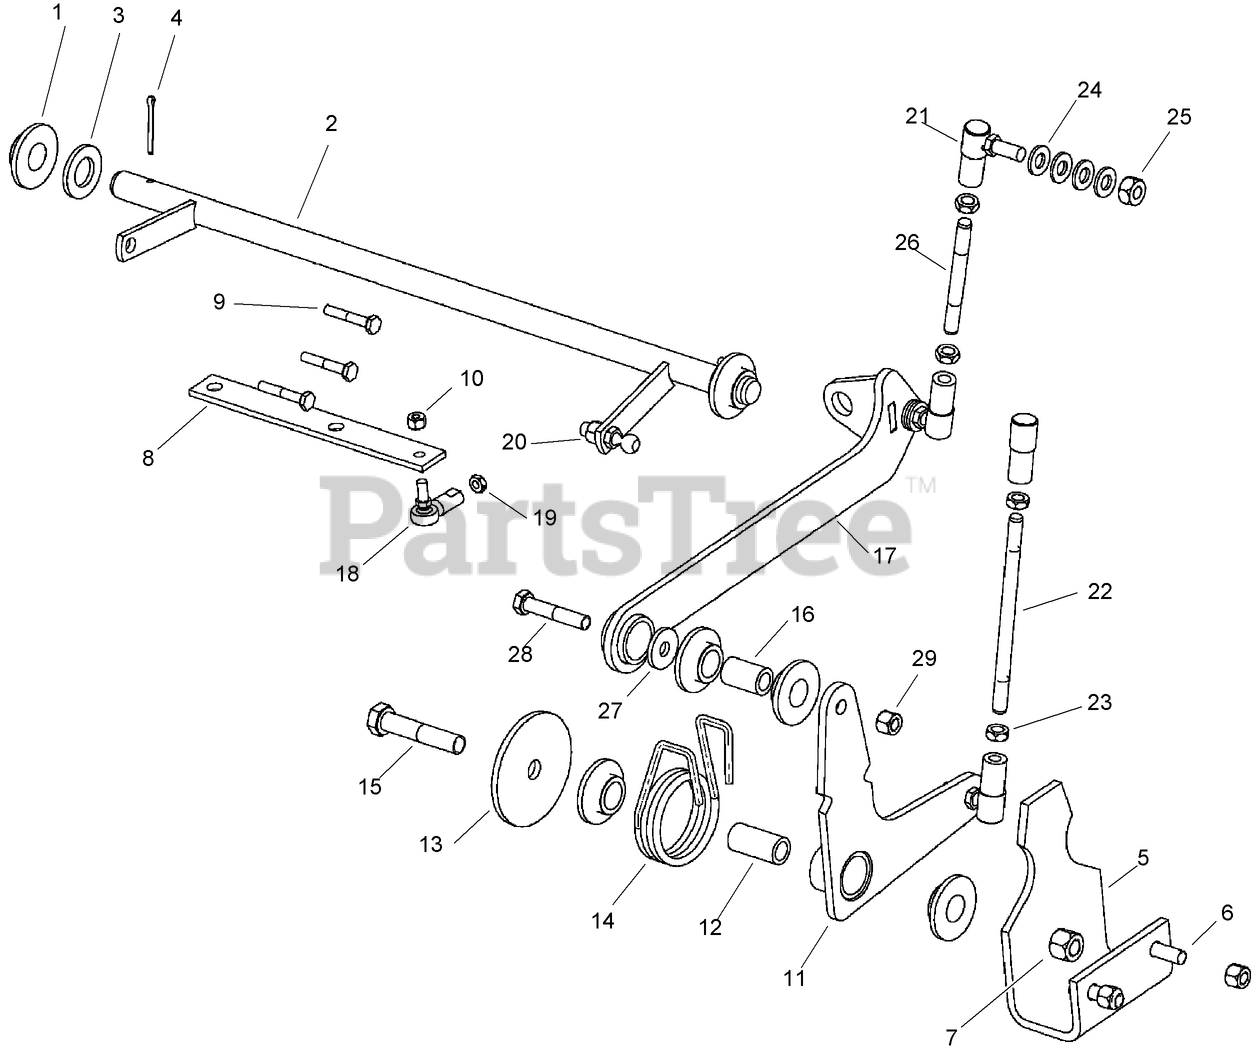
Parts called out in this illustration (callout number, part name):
1	BUSHING-INSERT, PLASTIC
2	WELDMENT-Control Shaft
3	WASHER-FLAT
4	PIN-Cotter, 1/8 x 1-1/4 in ZN
5	CHANNEL-Bellcrank Mounting
6	BOLT
7	NUT-HEX
8	LEVER-Pump Control
9	SCREW-HH
10	NUT-Prev Trq 1/4 GRA CAD DIRECT
11	PIVOT-BELLCRANK
13	WASHER-Special
15	SCREW-HH
16	SPACER-PIVOT, BELLCRANK
17	LINK-MOUNTING, CABLE
18	ROD END-FEMALE
19	NUT-Hex Jam 0.250-28 UNF GR5 ZND
20	NUT-HEX
21	JOINT-BALL
22	ROD-Linkage
23	NUT-JAM, HEX
24	WASHER-FLAT
25	NUT-Hex Hvy 3/8-24 UNF GR5 Pln
26	ROD-Linkage
28	BOLT-Hex Hd 3/8 x 2 GR5 ZND
29	NUT-HEX
